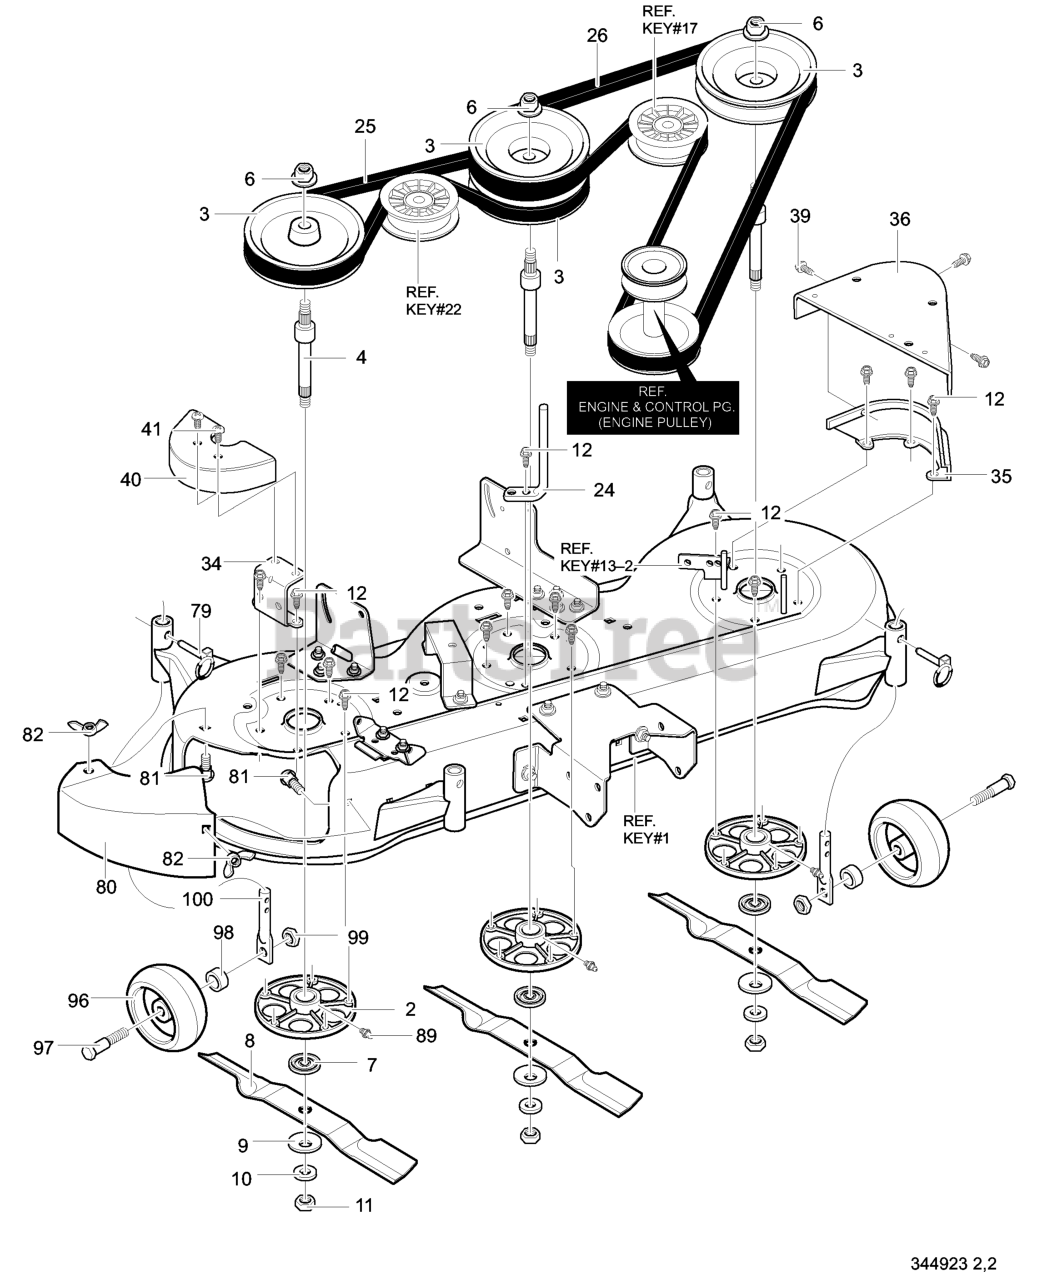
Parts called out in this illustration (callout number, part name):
2	HOUSING, JACKSHAFT
4	JACKSHAFT
6	NUT, 9/16-18
7	HUB, BLADE ADAPTER
8	BLADE, MULCHING
12	BOLT-3/8 X 1.25
24	ROD, BELT GUIDE
25	BELT, (37X66) 46" DECK
26	BELT, (37X89) 46" DECK
34	BRACKET, PULLEY COVER
35	BRACKET, PULLEY COVER
36	COVER, LEFT PULLEY
39	SCREW, 5/16-18 x 0.50
40	COVER, RIGHT PULLEY
79	PIN, LYNCH
80	PLATE, BLOCK OFF MULCH
81	BOLT, 5/16-18X .75
82	NUT, WING 5/16-18
89	ZERK, GREASE
96	WHEEL, GAUGE
99	NUT, JAM
100	ROD, GAUGE
